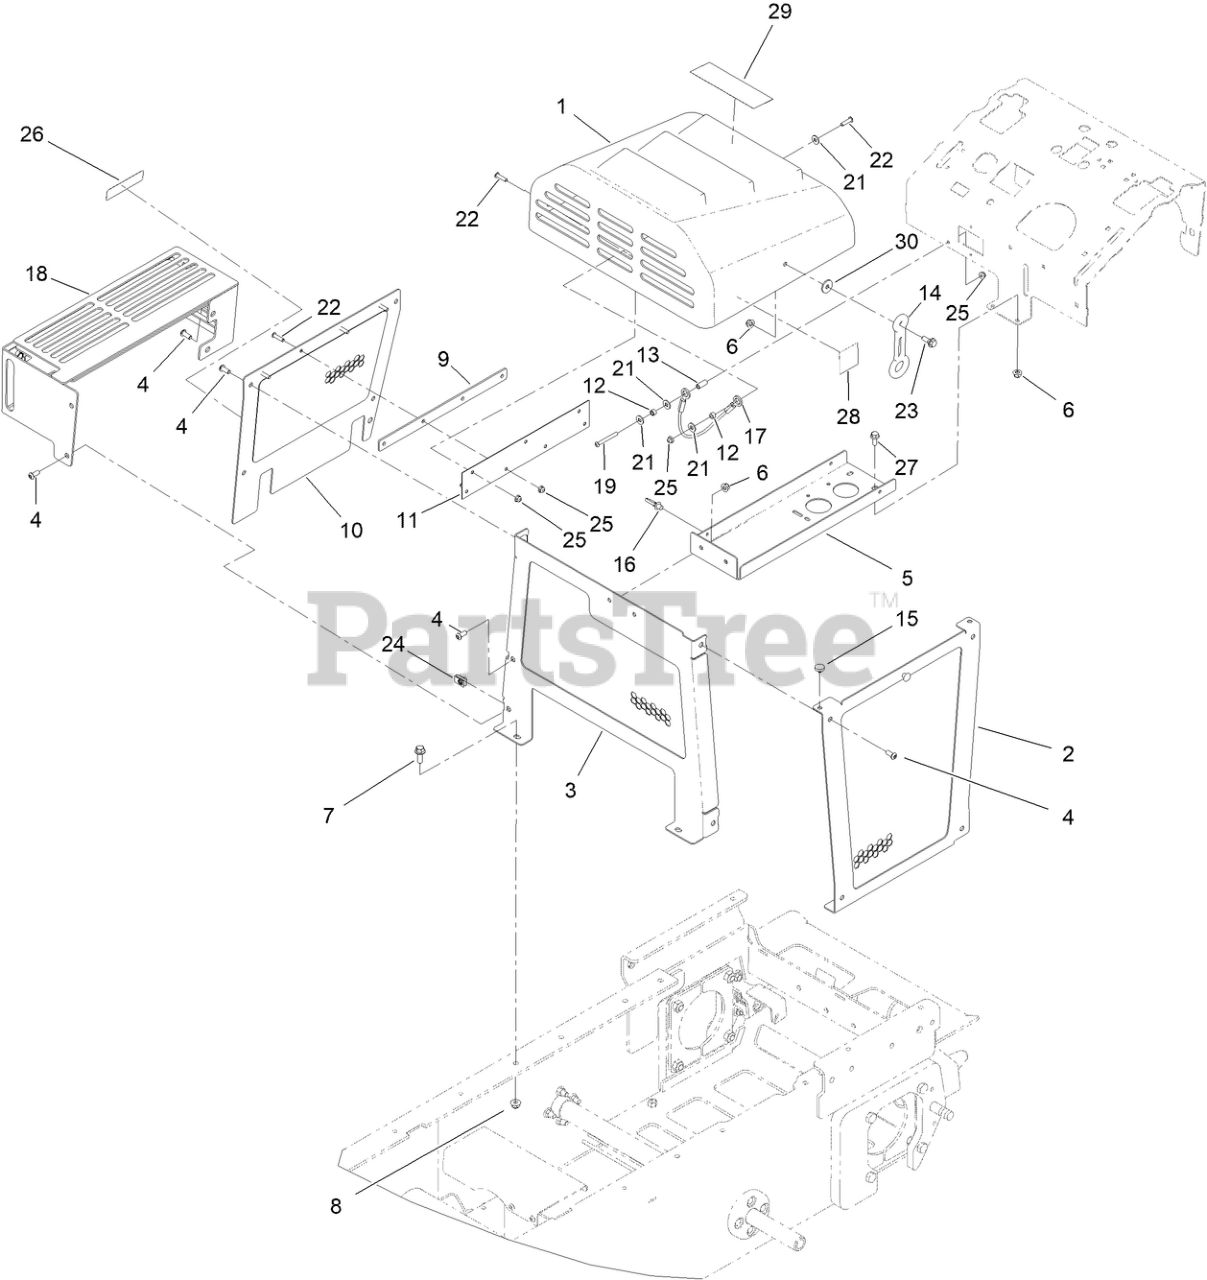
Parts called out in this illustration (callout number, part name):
1	HOOD ASM
2	PANEL-SIDE, LH
3	PANEL-FRONT (WELDED)
4	SCREW-HSBH
5	PLATFORM-BATTERY
6	NUT-HF, NI
7	SCREW-HHF
8	NUT-HF, NI
9	PLATE-SPACER, HOOD
10	PANEL-SIDE, UPPER
11	HINGE-HOOD
12	SPACER-BLADE, ROTOR
13	SPACER-BRAKE, PARKING
14	LATCH-RUBBER
15	BUMPER
16	CLIP-TIE
17	LANYARD
18	GUARD-MUFFLER
19	SCREW-HSBH
21	WASHER-FLAT
22	SCREW-HSBH
23	SCREW-SHOULDER
24	NUT-CLIP, U
25	NUT-HF
26	DECAL-ARRESTOR, SPARK
27	SCREW-HHF
28	DECAL-CPER0003
29	DECAL-RHHLG2X7
30	WASHER-FLAT
